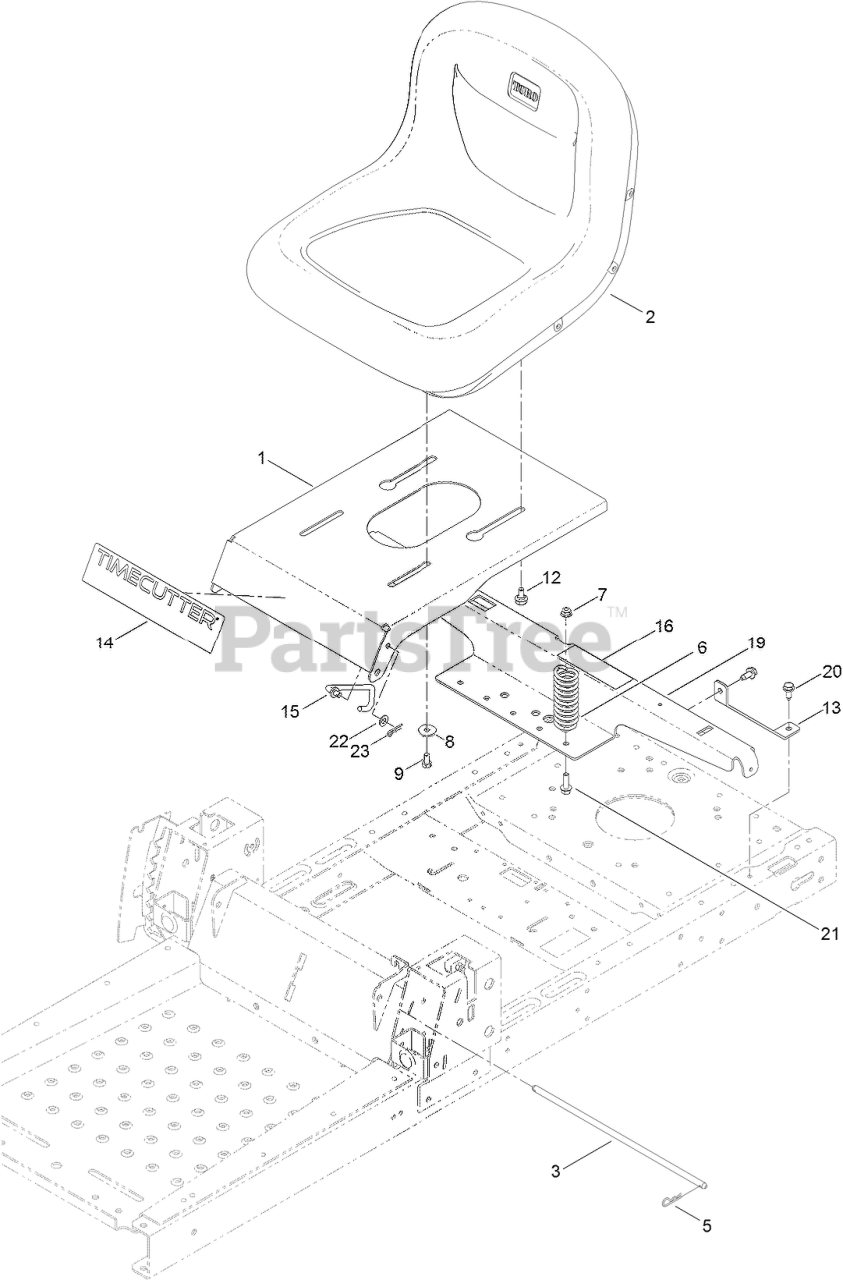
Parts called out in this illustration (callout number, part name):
1	PAN-SEAT
2	SEAT-15 INCH
3	ROD-PIVOT, NARROW
5	PIN-COTTER
6	SPRING-COMPRESSION
7	NUT-HF, NI
8	WASHER-PIVOT
9	SCREW-HH
12	BOLT-SHOULDER
13	SUPPORT-TANK, REAR
14	DECAL-TIMECUTTER
15	STOP-SEAT
16	DECAL-SERVICE, CE
19	SUPPORT-POD
20	SCREW-HWHTF
21	SCREW-HHF
22	WASHER-PLAIN
23	PIN-COTTER
